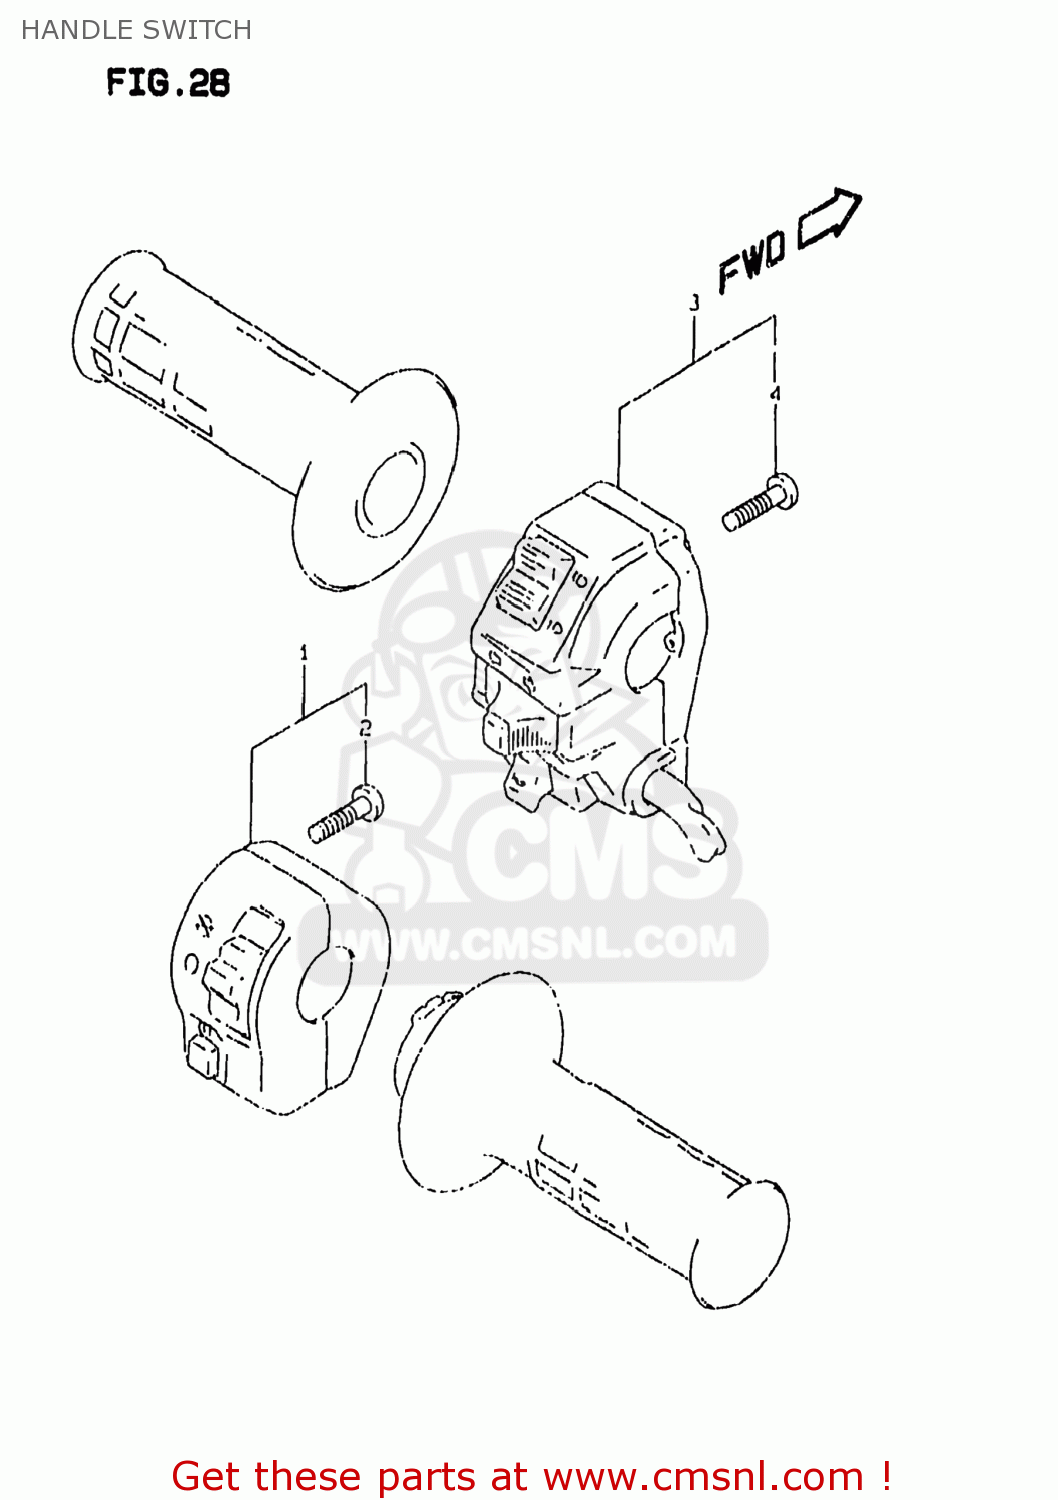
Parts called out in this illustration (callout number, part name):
1	SWITCH ASSY,HANDLE,R
2	SCREW
3	SWITCH ASSY,HANDLE,L
4	SCREW
